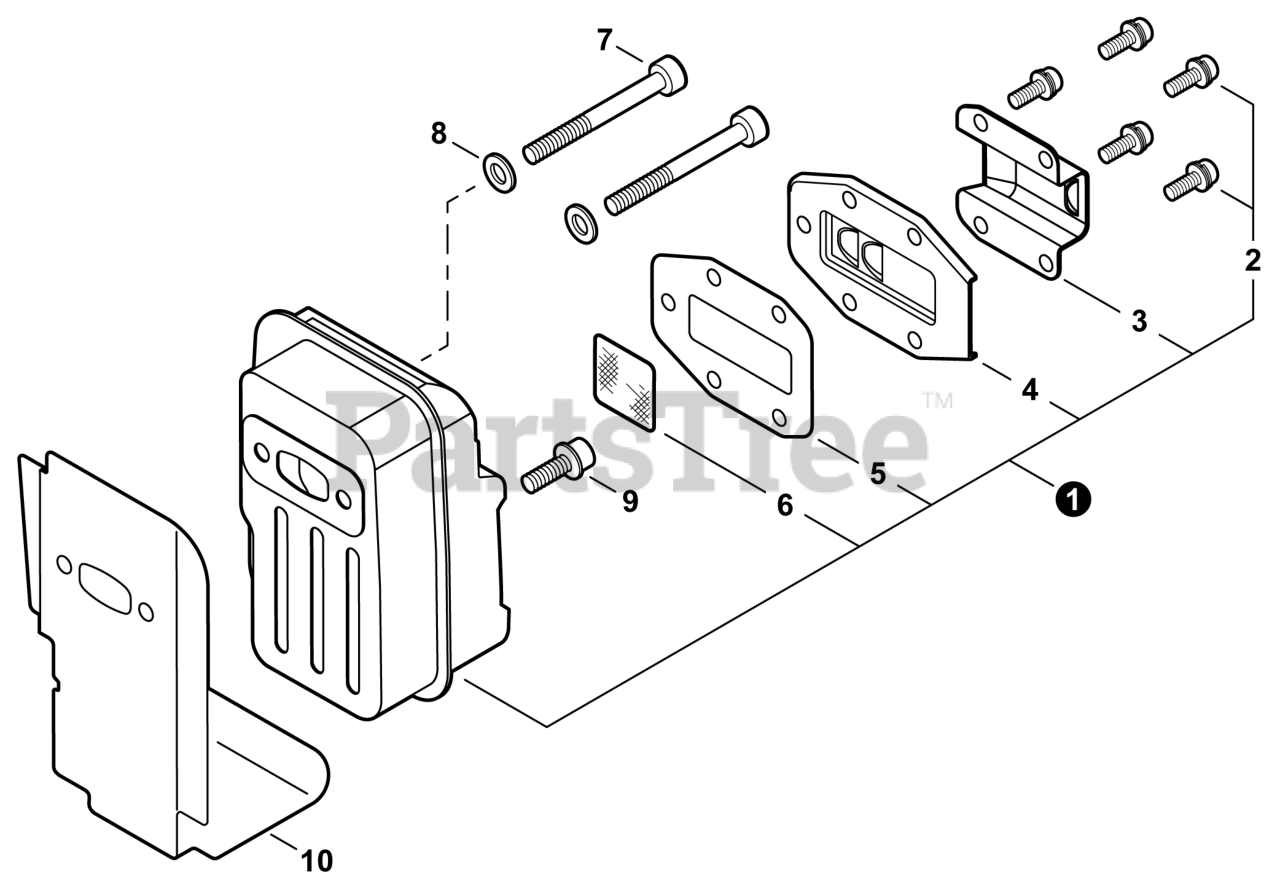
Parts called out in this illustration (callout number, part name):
1	MUFFLER ASSY
2	SCREW M4×8
3	OUTLET, EXHAUST
4	GUIDE, EXHAUST
5	GASKET, EXHAUST
6	SCREEN, SPARK ARRESTER
7	BOLT M5×55
8	WASHER SS 5 MM
9	BOLT 5×12
10	HEAT SHIELD, EXHAUST
